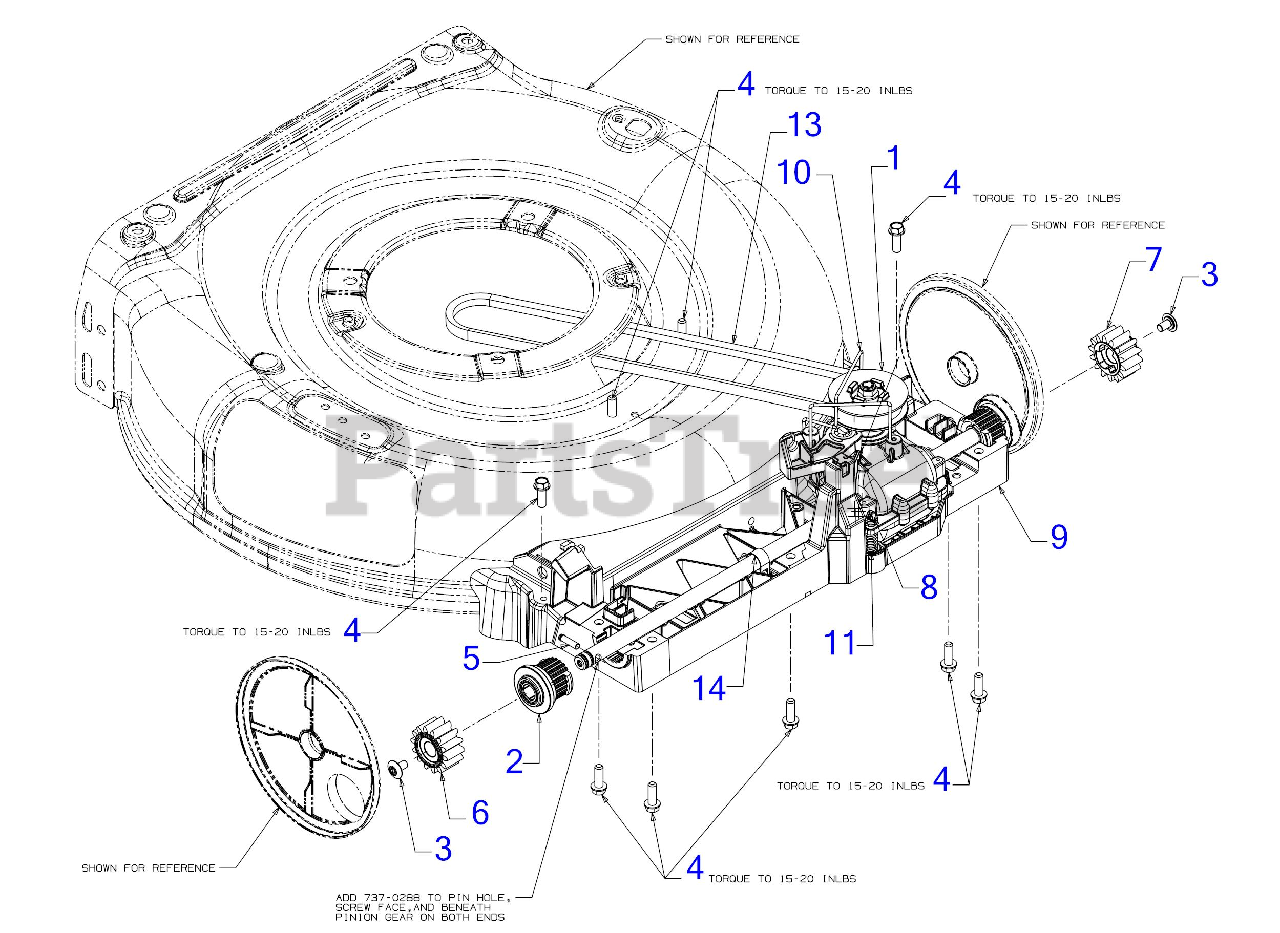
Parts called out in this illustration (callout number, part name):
1	FORWARD TRANSMISSION ASSEMBLY
2	SPHERICAL BEARING ASSEMBLY
3	SCREW 1/4-20 x .39
4	SCREW 1/4-15 x .750
6	SPUR GEAR 14T R
7	SPUR GEAR 14T L
8	SPRING COMPRESSION
9	LOWER TRAY
10	TRANSMISSION WIRE
11	COMPRESSION SPRING
13	V-BELT 3L 33.68
14	FRONT AXLE CLIP
